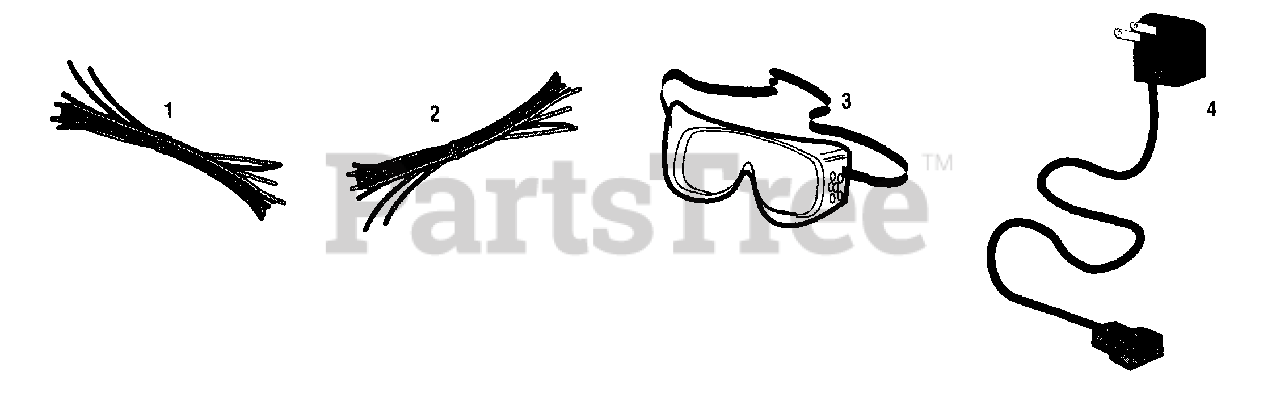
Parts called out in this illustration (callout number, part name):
1	Trimmer String Kit, .155"
2	Trimmer String Kit, .130"
3	Safety Goggles
4	Battery Charger
